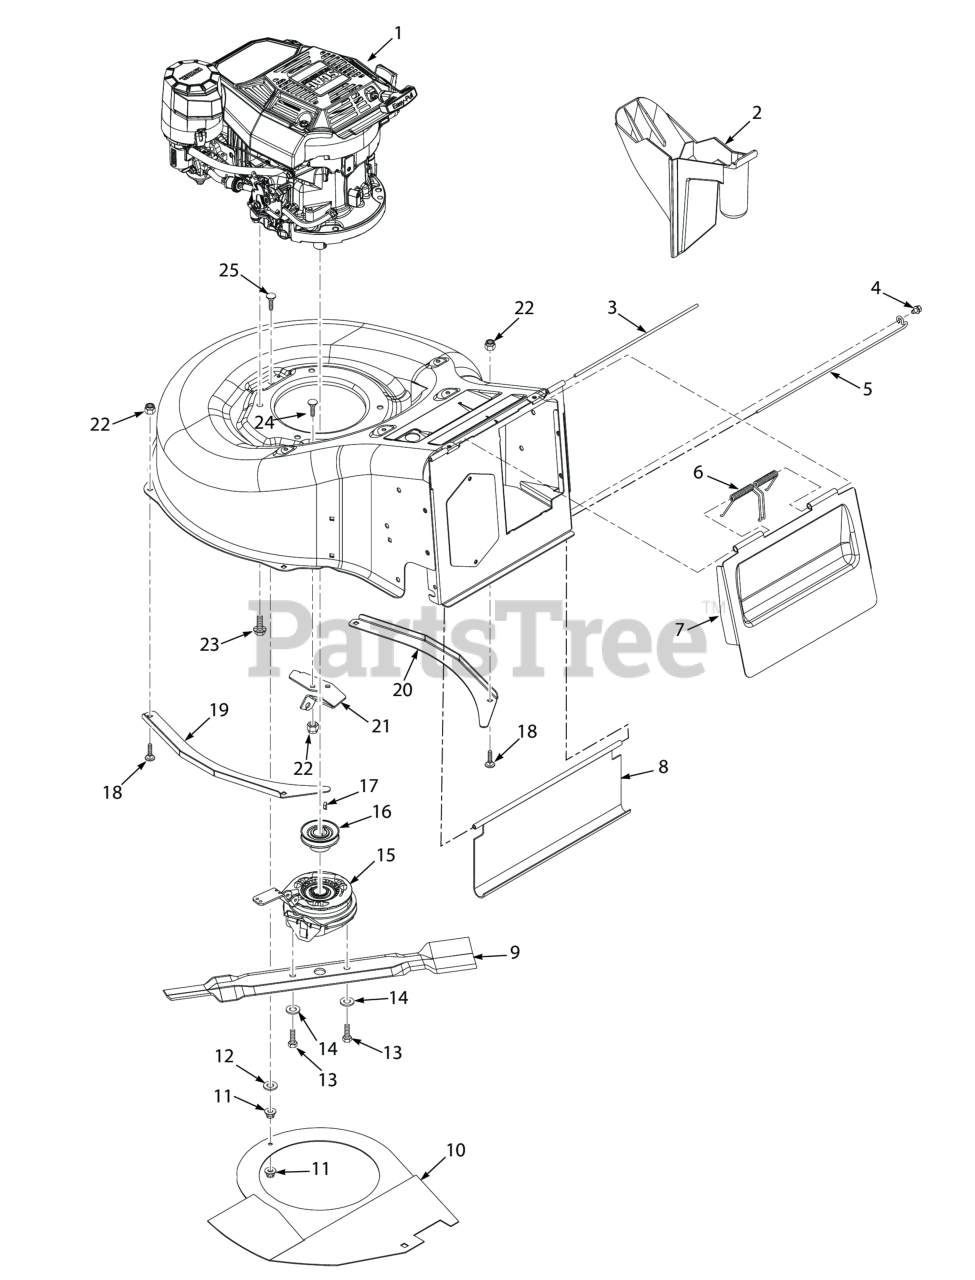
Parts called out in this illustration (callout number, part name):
1	Engine, 7CV
2	Plug, Mulch
3	Pin, Pivot
4	Screw, 1/4-20 x .375"
5	Rod, Support Spring
6	Spring, Rear Cover
7	Cover, Rear
8	Trail Shield
9	Cutter Blade, 21"
10	Belt, Cover
11	Nut, Flanged Elastic Stop 1/4-20
12	Flatwasher, 5/16-.375 x .875 x .083 (35BV & 37BV-EFI)
13	Bolt, Hex Head 3/8-16 x 1"
14	Flatwasher, 3/8 (.391 x .938 x .105 HD) Grade 8
15	Clutch, BBC
16	Pulley, Transmission
17	Key, 3/16 x 3/16 x .313
18	Bolt, Carriage 1/4-20 x 1/2"
19	Guard, LH
20	Guard, RH
21	Anti-Rotation Bracket
22	Nut, Flanged Elastic Stop 1/4-20
23	Screw, 3/8-19 x 1" Self Tapping
24	Serr. Fl. Hex Head CPSCR, 1/4-20 x 3/4"
25	Bolt, Carriage, 1/4-20 x 1-1/4"
